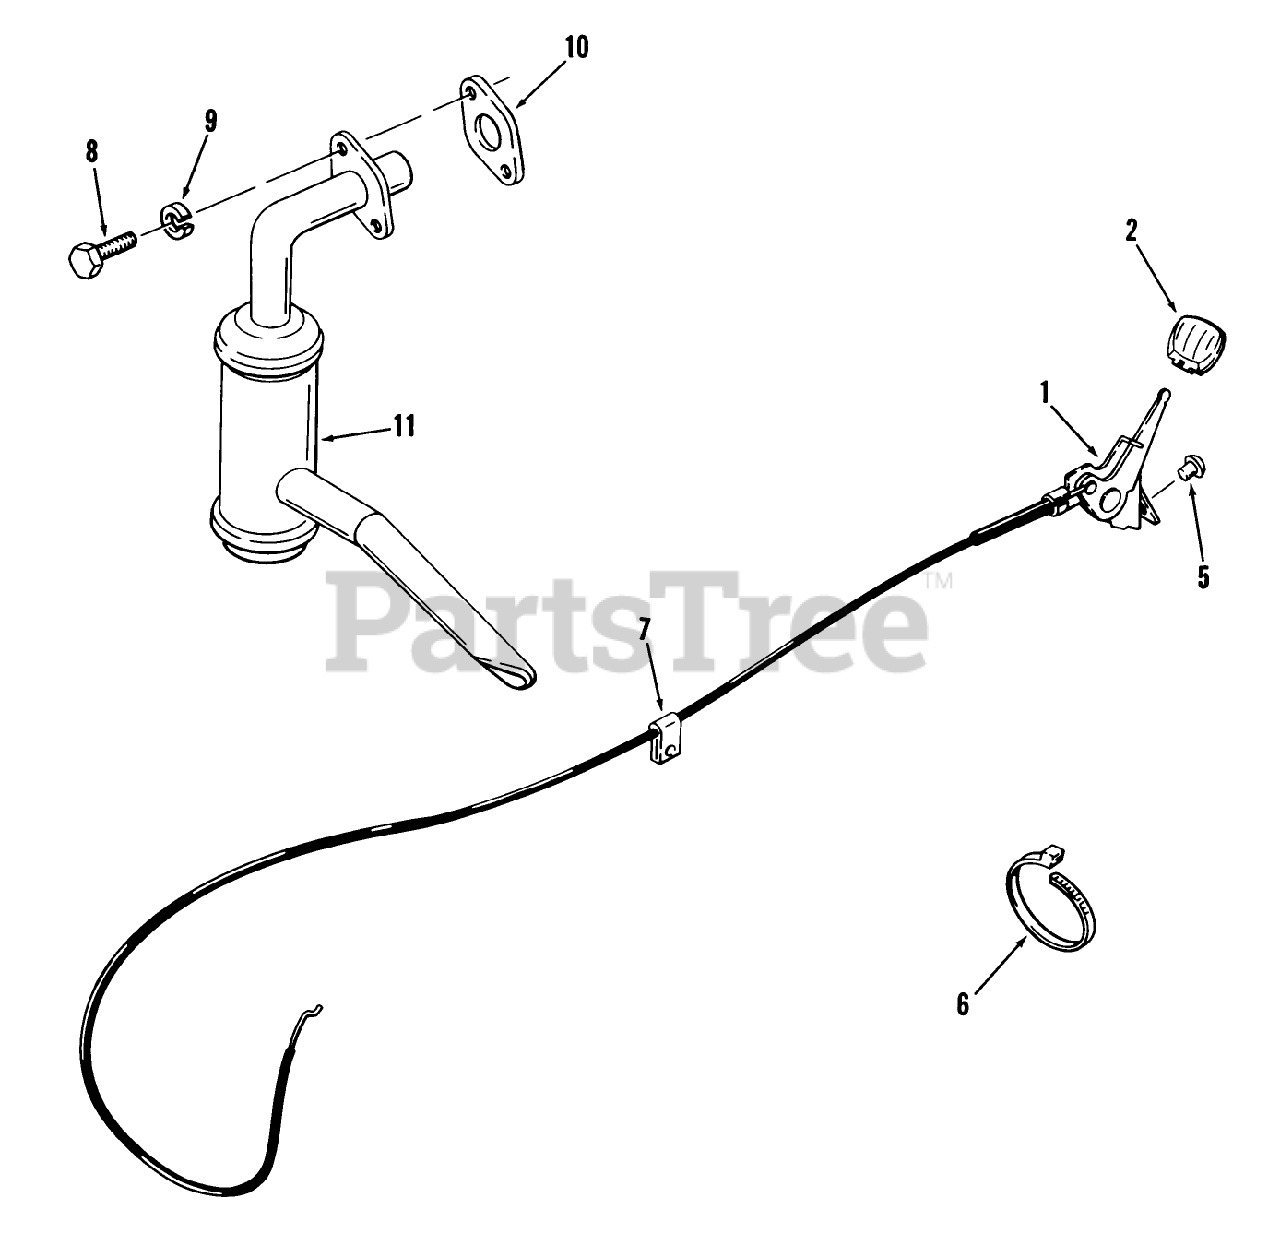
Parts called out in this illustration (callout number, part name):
2	KNOB-THROTTLE
5	Pip Rivet
7	THROTTLE CONTROL CLP
10	USE BRIGGS #270917
